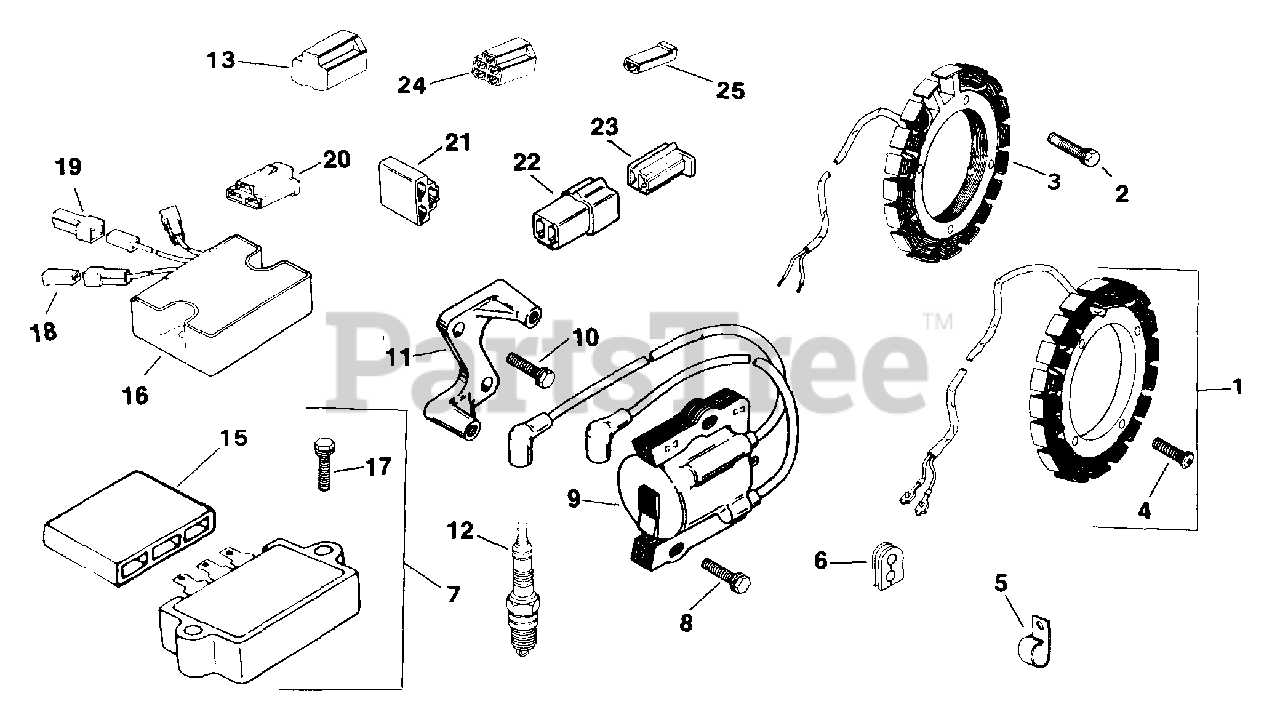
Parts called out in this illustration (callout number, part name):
1	KIT, 15 / 20 AMP STATOR
2	SCREW, WSH HD TAP #10-24X3/4" USE 25 086 97-S
6	GROMMET - (#DSC)
7	KIT, REGULATOR/RECTIFIER
8	SCREW, WSH HD 1/4-20X1"
10	SCREW, WSH HD 1/4-20X7/8" - DISCONTINUED
11	BRACKET - DISCONTINUED
12	SPARK PLUG
15	CONNECTOR, BODY (KM)-USE 25 155 41-S
17	SCREW, SEMS 1/4-20X5/8" USE 25 086 539-S
21	CONNECTOR
